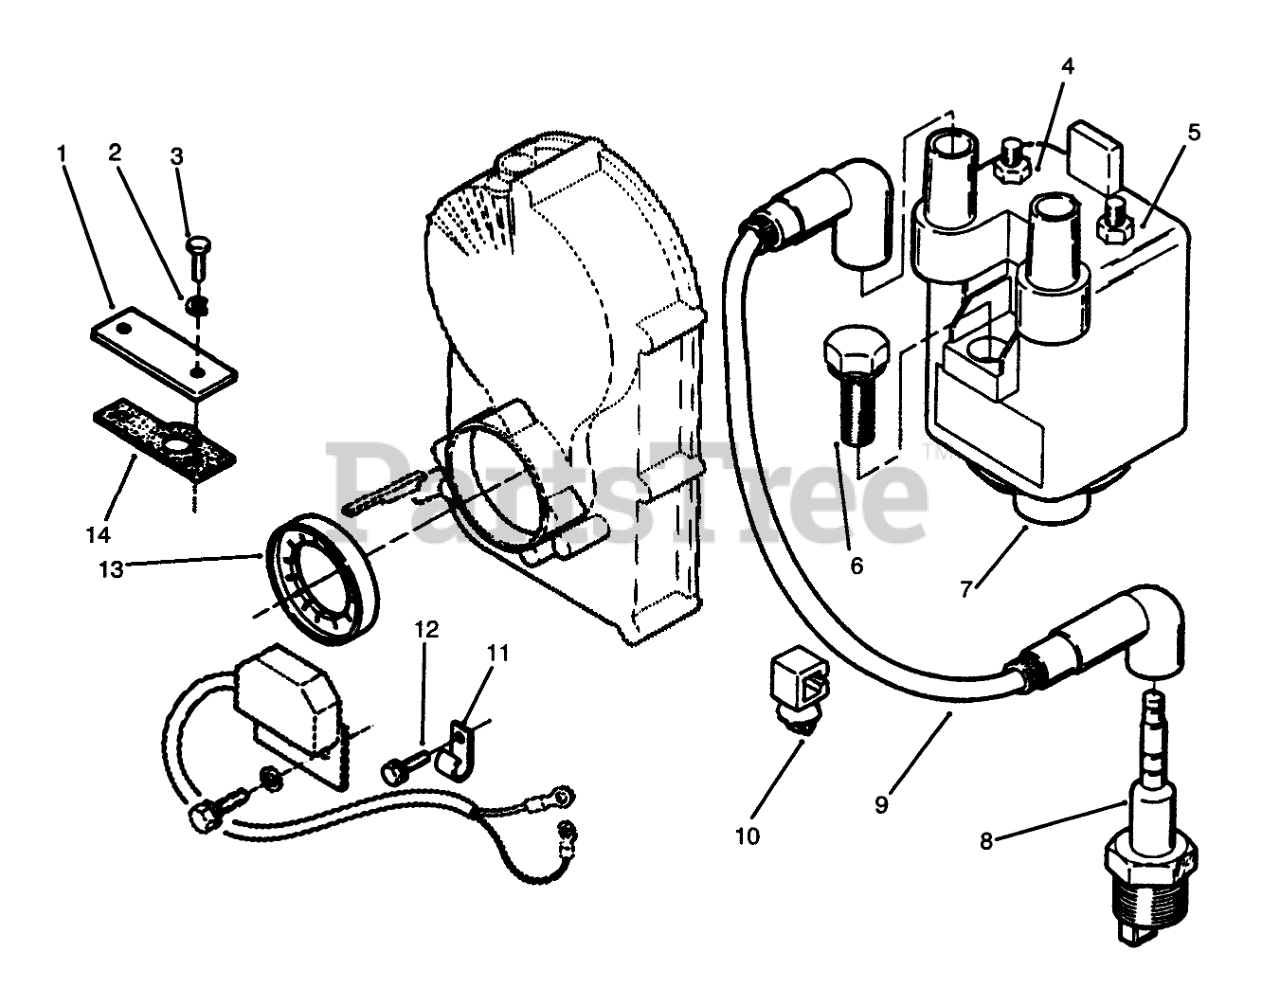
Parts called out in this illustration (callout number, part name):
1	PLATE-COVER
2	WASHER-FLAT
3	SCREW - CAP HEX HEAD
4	NUT-HEX FLANGE
5	NUT-HEX FLANGE
6	HEX-HEAD CAP SCREW
7	Coil-Battery Ignition (Incl. Ref. #4-5)
8	SPARK PLUG
9	Wire-Plug
10	WIRE ROUTING CLIP
11	CLIP-WIRE
12	SCREW-HH
13	ROTOR-IGNITION
14	Gasket-Plate
